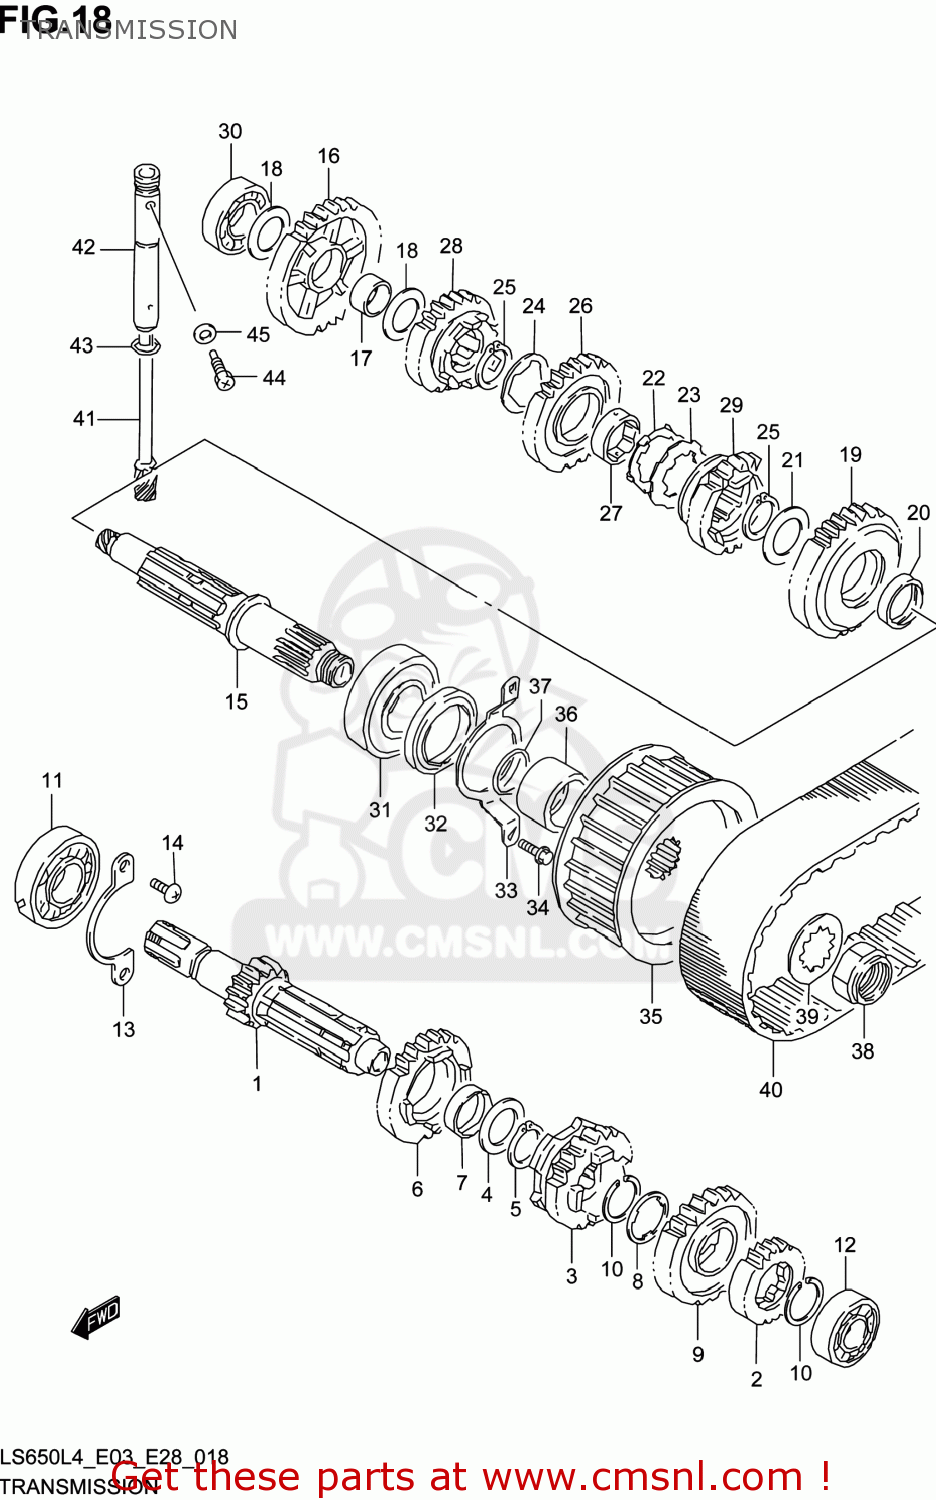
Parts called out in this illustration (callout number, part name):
1	SHAFT,COUNTER(NT:15)
2	GEAR,2ND DRIVE(NT:19)
3	GEAR,3RD DRIVE(NT:21)
4	WASHER
5	RING,SNAP
6	GEAR,4TH DRIVE(NT:23)
7	BUSH
8	WASHER,LOCK
9	GEAR,5TH DRIVE
10	CIRCLIP
11	BEARING(22X56X16)
12	BEARING(17X40X12)
13	RETAINER,CNTR SHAFT BEARING
14	SCREW
15	SHAFT,DRIVE
16	GEAR,1ST DRIVEN(NT:35)
17	BUSH(20X24X13)
18	SHIM(20X30X1)
19	GEAR,2ND DRIVEN
20	BUSH(25X29X8)
21	WASHER
22	WASHER
23	WASHER,LOCK
24	WASHER,LOCK
25	RING,SNAP
26	GEAR,3RD DRIVEN
27	BUSH,DRIVEN GEAR
28	GEAR,4TH DRIVEN(NT:22)
29	GEAR,5TH DRIVEN
30	BEARING(20X42X12)
31	BEARING(25X62X17)
32	SEAL,OIL(36X50X6)
33	RETAINER,DRIVE SHAFT OIL SEAL
34	BOLT
35	PULLEY,FR
36	SPACER,FR PULLEY
37	O RING(D:2.4,ID:23.7)
38	NUT
39	WASHER,LOCK
40	BELT,DRIVE
41	GEAR,SPEEDOMETER DRIVEN
42	SLEEVE,TACHOMETER DRIVEN GEAR
43	O RING(D:1.3,ID:9.6)
44	BOLT(6X10)
45	GASKET(6.2X11X1).2 (NAS)
